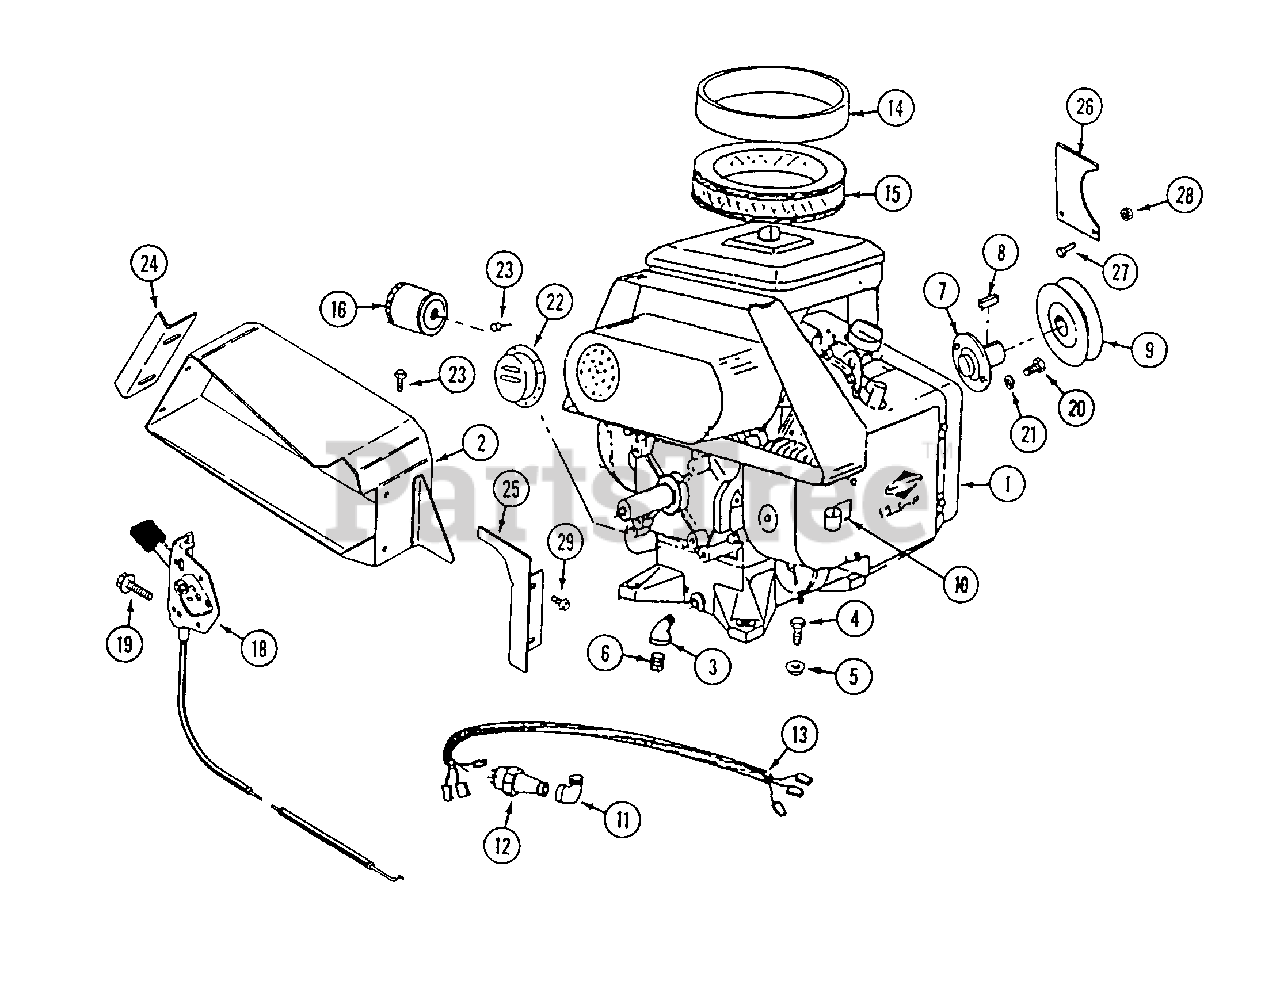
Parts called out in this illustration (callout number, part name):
1	ENGINE - Briggs and Stratton
2	DUCT - air
3	ELBOW - street 3/8"
4	BOLT - 5/16" - 18 x 1-1/4"
5	NUT - 5/16" - 18
6	PLUG - pipe 3/8"
8	KEY - 1/4" x 1/4" x 1"
9	PULLEY - drive
10	RETAINER - starter cable
11	ELBOW - street 1/8"
12	UNIT - oil sending
13	HARNESS - wire
14	PRECLEANER
15	FILTER - air
16	FILTER - oil
19	SCREW - #12 x 1/2"
20	LOCKWASHER - 3/8"
21	BOLT - 3/8" - 16 x 1"
22	DEFLECTOR - exhaust
23	SCREW - #8 - 32 x 3/8"
24	DEFLECTOR - front extension
25	DEFLECTOR - rear extension
26	RETAINER - drive belt
27	BOLT - 1/4" - 20 x 1"
28	NUT - 1/4" - 20 lock
